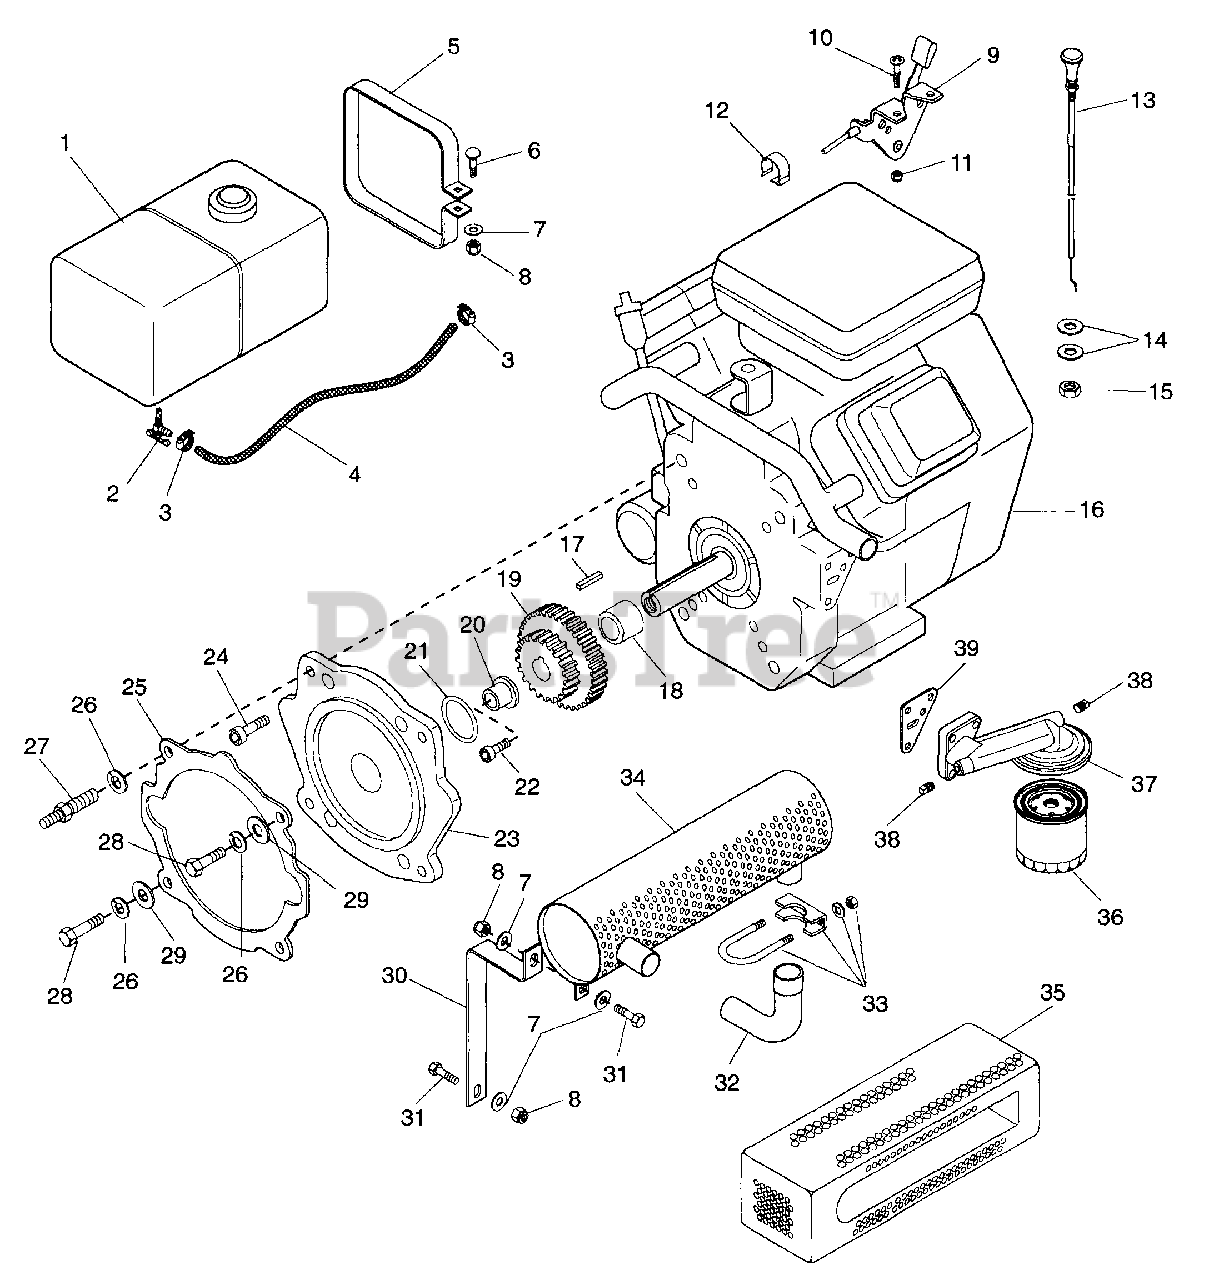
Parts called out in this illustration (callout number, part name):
1	Tank, Fuel
2	Valve & Strainer
3	Hose Clamp
4	Gas Line - Bulk
5	Strap, Fuel Tank
6	Bolt, Round Head Square Neck .25-20 x 1.75
7	Washer-Flat-Steel .312 x .734 x .065
8	Nut-Locking-Nylon .250-20
9	Control, Choke
10	Screw-Machine 10-24 x .50
11	Nut-Locking 10-24
12	Clamp
13	Lever, Choke Control
14	Washer-Flat-Steel .406 x .812 x .065
15	Nut-Jam .375-24
16	Engine - 16 HP B & S
17	Key-Square .248 x 1.0 x .248
18	Bushing-Flange 1.05 x 1.31 x 1.54
19	Gear, B & S Engine
20	Pilot, Gear
21	O-Ring 1.850 x 2.270 x .210
22	Screw-Machine .38-24 x 1.00
23	Adapter B & S Engine
24	Screw-Socket Head .44 - 14 x 1.00
25	Gasket, Chassis to Adapter
26	Washer-Lock .438 x .133
27	Stud
28	Bolt-Hex .44-14 x 1.50
29	Washer-Flat-Steel .469 x .938 x .065
30	Bracket, Exhaust
31	Bolt-Hex .25-20 x 1.00
32	Elbow
33	Clamp-Muffler 1.25
34	Muffler
35	Muffler Guard
36	Filter, Oil
37	Oil Filter Adapter
38	Plug-Pipe 1/16 - 27
39	Gasket, Oil Filter Adapter
